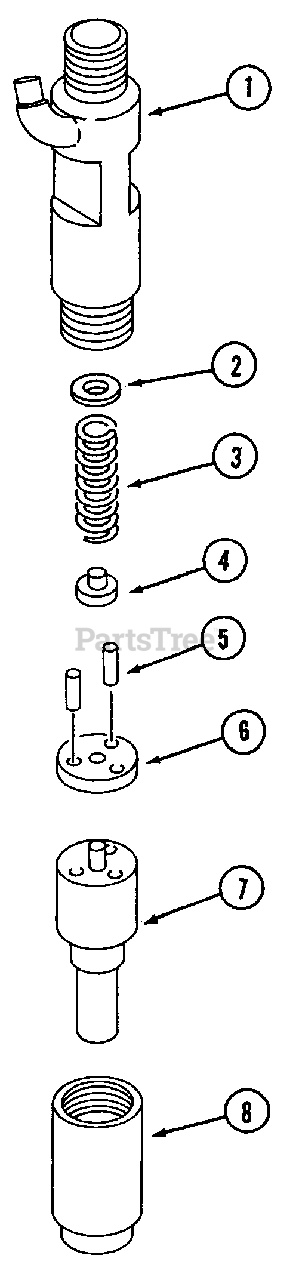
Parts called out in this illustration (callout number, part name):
1	Nozzle Ass'y.
1	Body Sub Ass'y.
2	Washer, t=1.2
3	Spring, Pressure
4	Pin, Pressure
5	Pin, Straight
6	Packing, Tip
7	Nozzle Ass'y.
8	Nut
